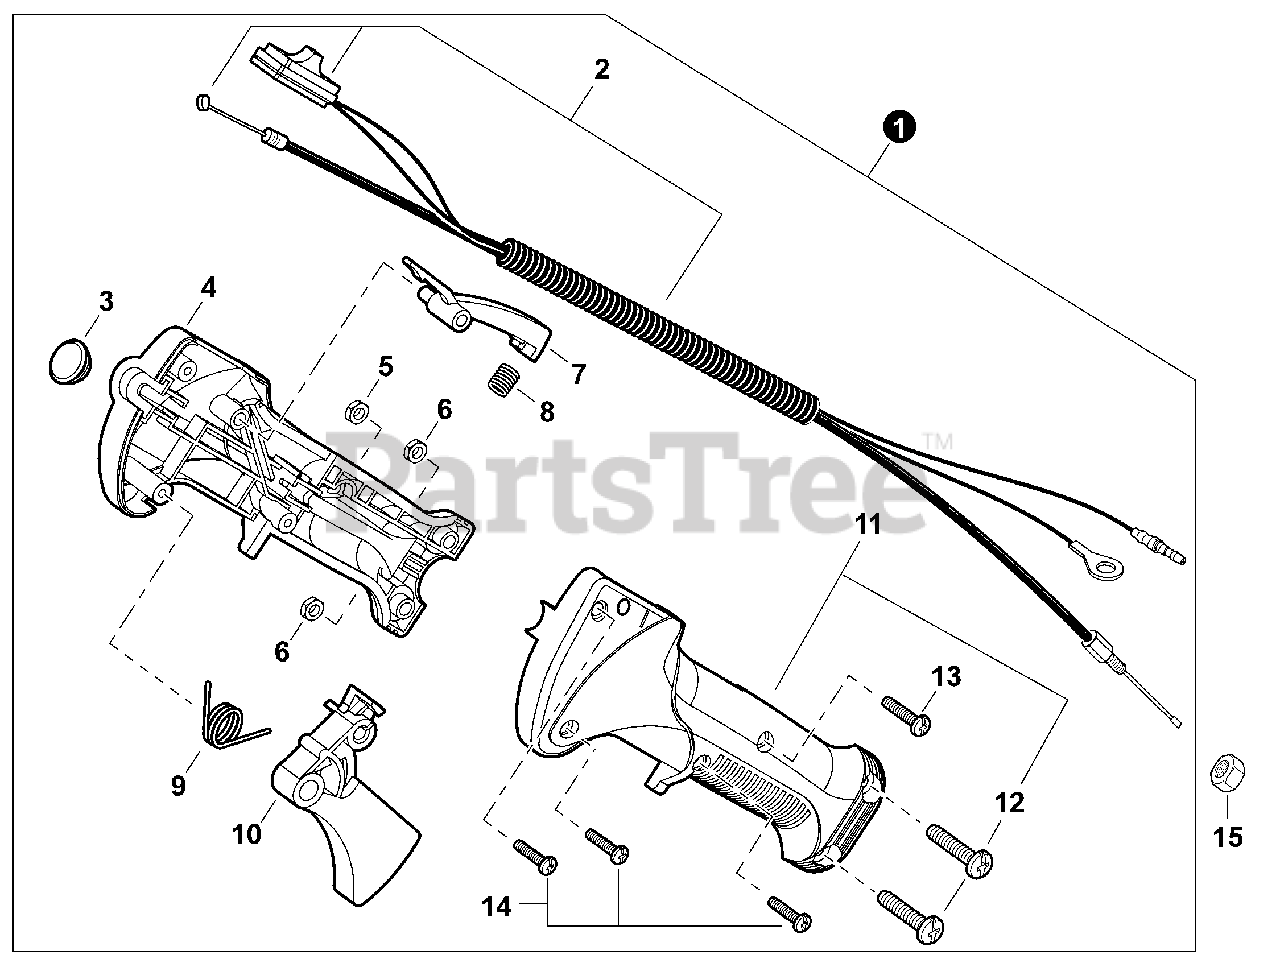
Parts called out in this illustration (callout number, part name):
1	THROTTLE CONTROL ASSY
2	CABLE ASSY, CONTROL
3	PLUG, RUBBER
4	CONTROL HANDLE - RIGHT
7	LOCKOUT, THROTTLE
8	SPRING, COMPRESSION
9	SPRING, TORSION
10	TRIGGER, THROTTLE
11	CONTROL HANDLE KIT
12	SCREW M5×22
13	SCREW M4×23
14	SCREW, TAPPING 4×16
